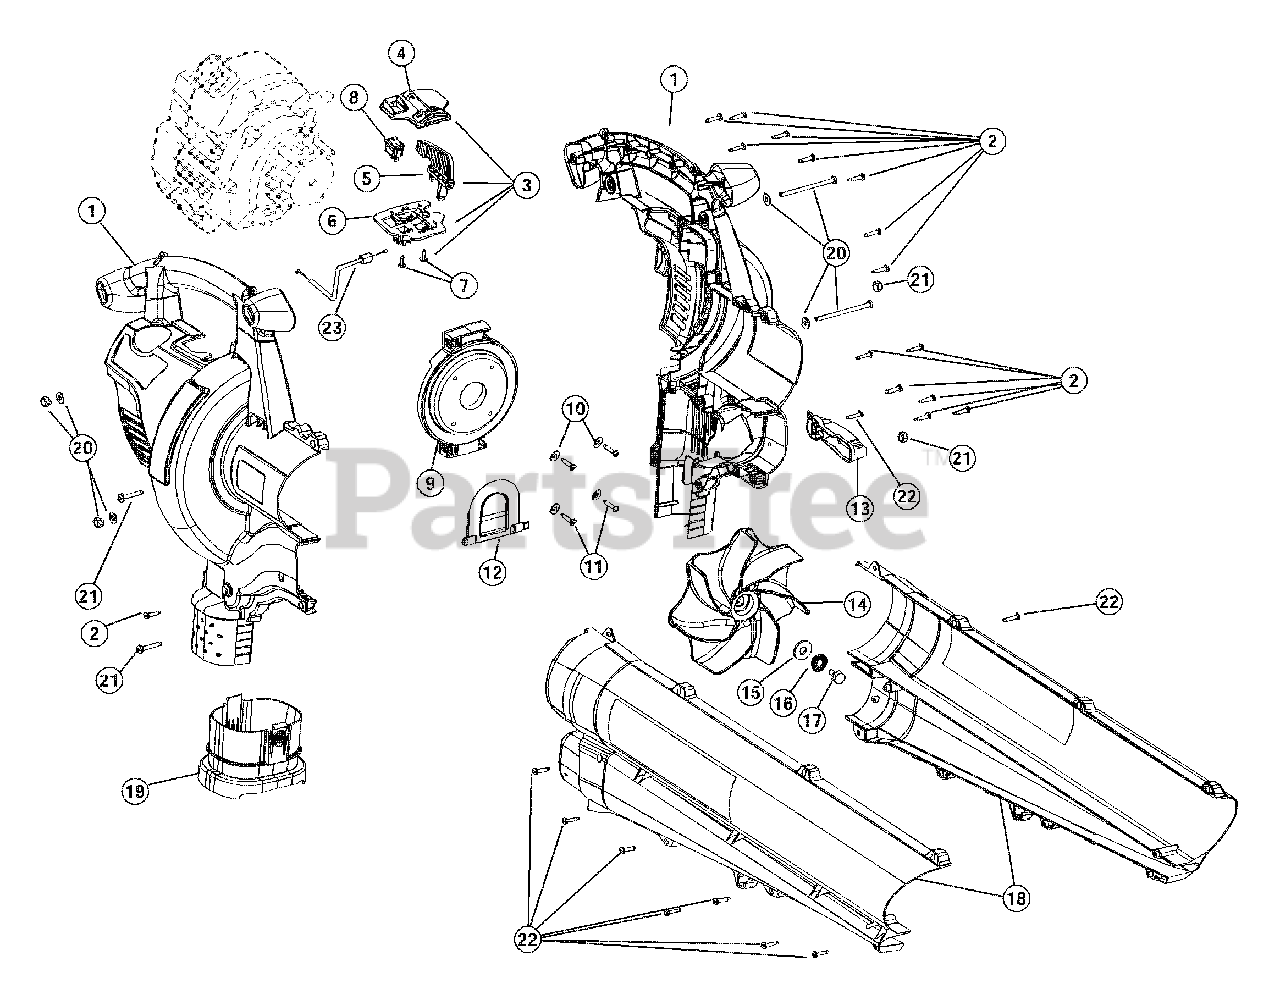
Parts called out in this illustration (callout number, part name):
1	Engine Cover Assembly
2	Cover Screw
3	Throttle Control Assembly
4	Upper Throttle Control Plate
5	Throttle Control Lever
6	Lower Throttle Control Plate
7	Screw, Plastic
8	Rocker Switch Assembly
9	Engine Mounting Plate
11	Screw
12	Mode Control Flapper
13	Mode Control Lever
14	Impeller Blade
15	Washer
16	Lock Washer
18	Blower/Vac Tube Assembly
19	Vacuum Bag Adapter
20	Mounting Plate Hardware
21	Blower/Vac Tube Mounting Hardware
23	Throttle Cable
